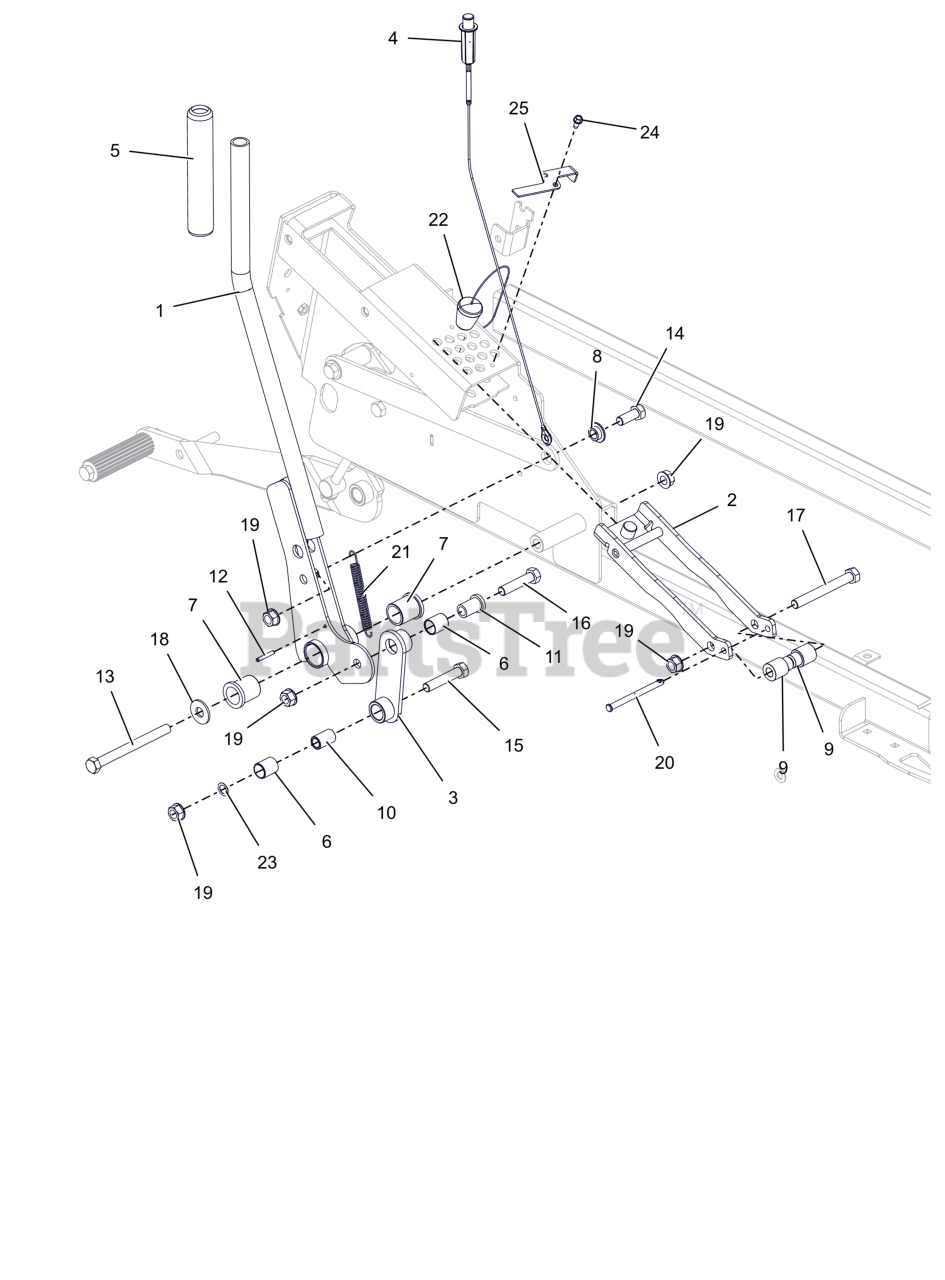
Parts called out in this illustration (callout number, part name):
1	WLDMT, HOC LEVER
2	WLDMT, HOC BRACKET
3	LINK, HOC LEVER
4	CABLE, HOC PUSH CONTROL
5	GRIP, DECK LIFT
6	BRG, .750 X .875 X 1.000
7	BSHG-FLG 1.00X1.25X1.50X1.50
8	BSHG, FLG .515X.750X.360X1.12
9	BSHG,FLG
10	SPCR, SLV .532 X .750 X 1.150
11	BSHG-FLG .515X.746X1.290X1.000
12	PIN-ROLL .188X1.25
13	BLT,HEX .50-13X5.50 G5 ZCC
14	BLT,HEX .50-13X1.25 G5 ZCC
15	BLT, HEX .50-13X2.50 G5 ZCC
16	BLT, HEX .50-13X2.25 G5 ZCC
17	BLT, HEX 0.5-13X4.25 GR5 ZCC
18	WSHR,FLT .563X1.375X.109 ZCC
19	NUT-LK-CTR-FLG .500-13 GG ZCC
20	PIN, SLIC-.3125X4.015X3.625 -ZCC
21	SPRING,EXT,.061X.50X3.0
22	PIN, MAGNETIC .50X2.50
23	WASHER, .500X.750X.020 THRUST
24	SCR-TAP .25-20X.50 HWH ZCC
25	BLOCK, HOC SELECTION (BLACK)
